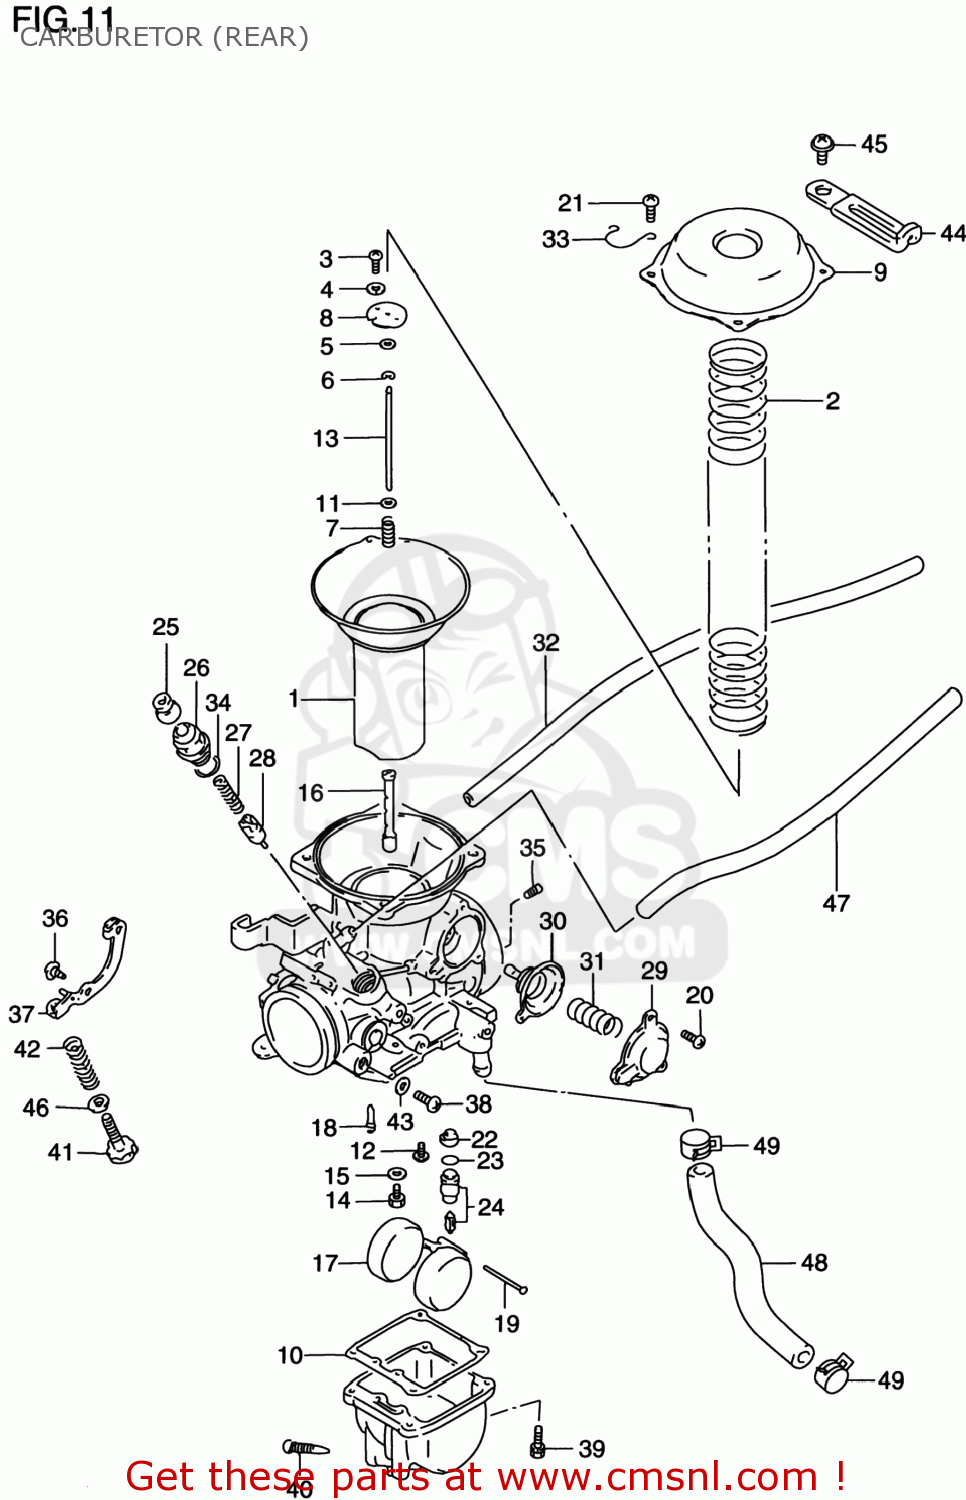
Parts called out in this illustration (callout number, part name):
1	DIAPHRAGM,CARBURETOR
2	SPRING,DIAPHRAGM
3	SCREW
4	WASHER,LOCK
5	RING
6	CLIP
7	SPRING
8	PLATE
9	COVER,DIAPHRAGM
10	GASKET,FLOAT CHAMBER (NAS)
11	WASHER
12	JET,PILOT(45)
13	NEEDLE,JET
14	JET,MAIN(132.5)
15	WASHER
16	JET,NEEDLE(P-7M)
17	FLOAT
18	SCREW
19	PIN,FLOAT
20	SCREW
21	SCREW
22	FILTER
23	O-RING,NEEDLE VALVE
24	VALVE ASSY,NEEDLE
25	CAP
26	HOLDER,GUIDE
27	SPRING
28	PLUNGER,STARTER
29	COVER
30	DIAPHRAGM ASSY
31	SPRING
32	HOSE(5X8.2X600)
33	CLIP
34	O RING
35	JET,AIR(65)
36	SCREW
37	LEVER ASSEMBLY
38	SCREW
39	SCREW
40	SCREW,DRAIN
41	ADJUSTER
42	SPRING
43	GASKET,DRAIN PLUG (NAS)
44	CLAMP(L:80)
45	SCREW
46	WASHER
47	(CA) HOSE SET,FUEL
48	HOSE,FUEL PUMP & CARBURETOR
49	CLIP
50	O RING,PILOT AIR SCREW
51	WASHER
52	SPRING
53	SCREW,PILOT
54	PLUG
